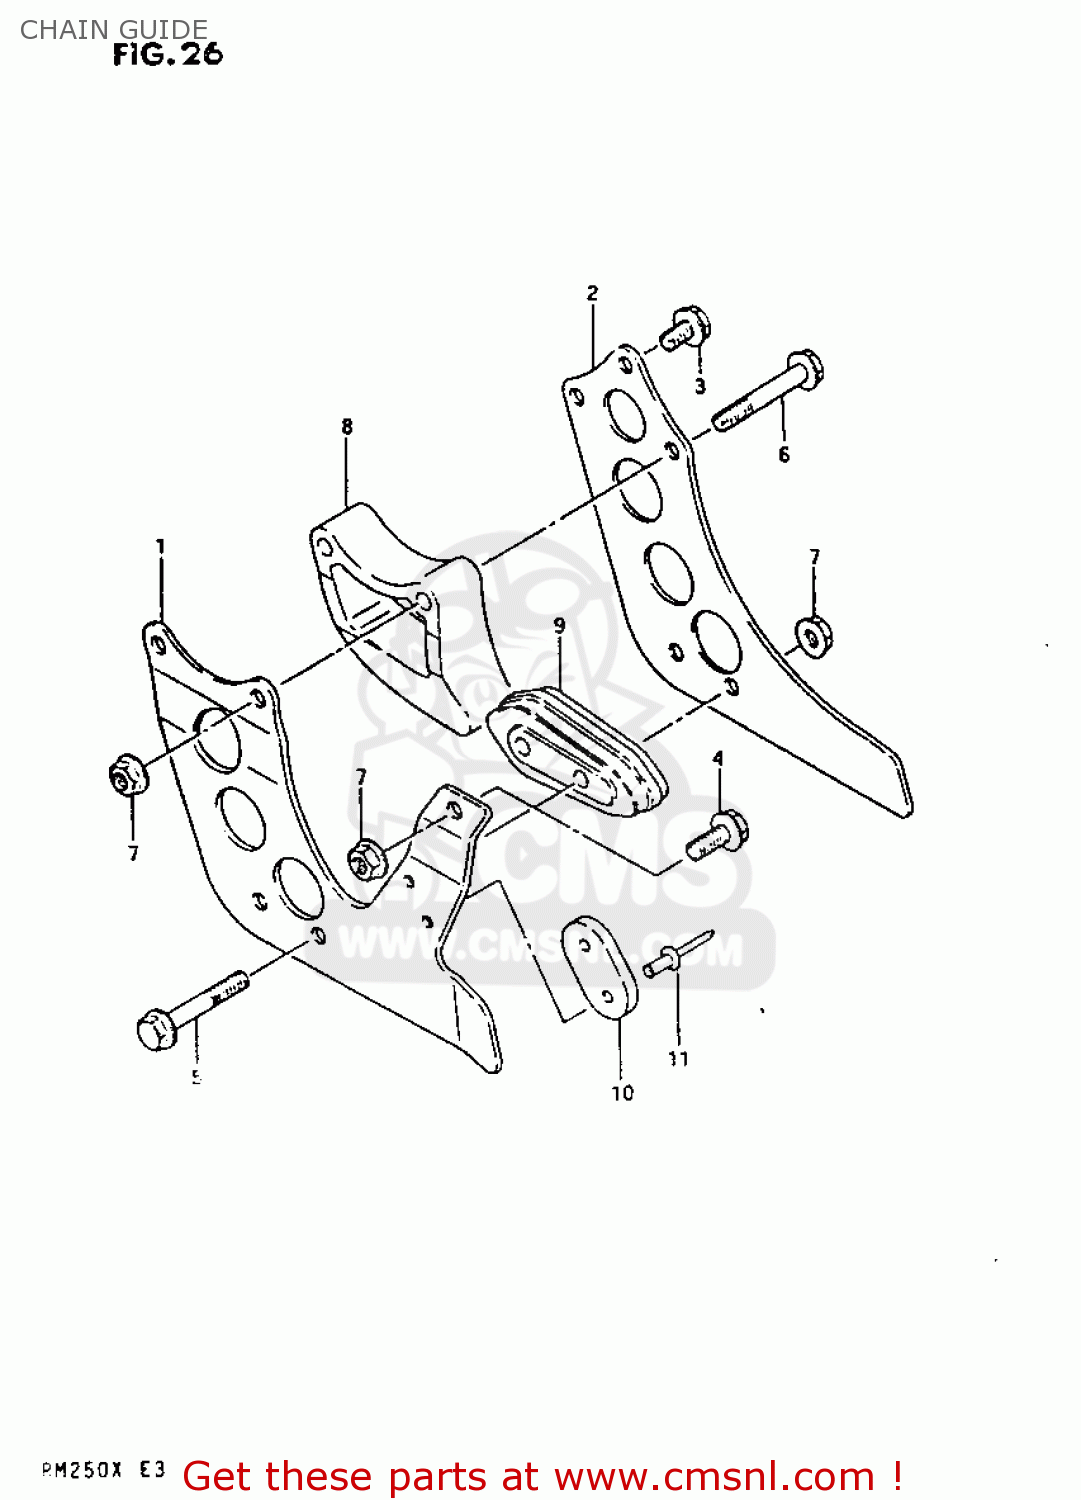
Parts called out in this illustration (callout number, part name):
1	PLATE,OUTER
2	PLATE,INNER
3	BOLT 6X12
4	BOLT 6X16
5	BOLT
6	BOLT,UNDER
7	NUT
8	DEFENSE,CHAIN GUIDE UPR
9	DEFENSE,CHAIN GUIDE
10	PAD,CHAIN GUIDE
11	RIVET
